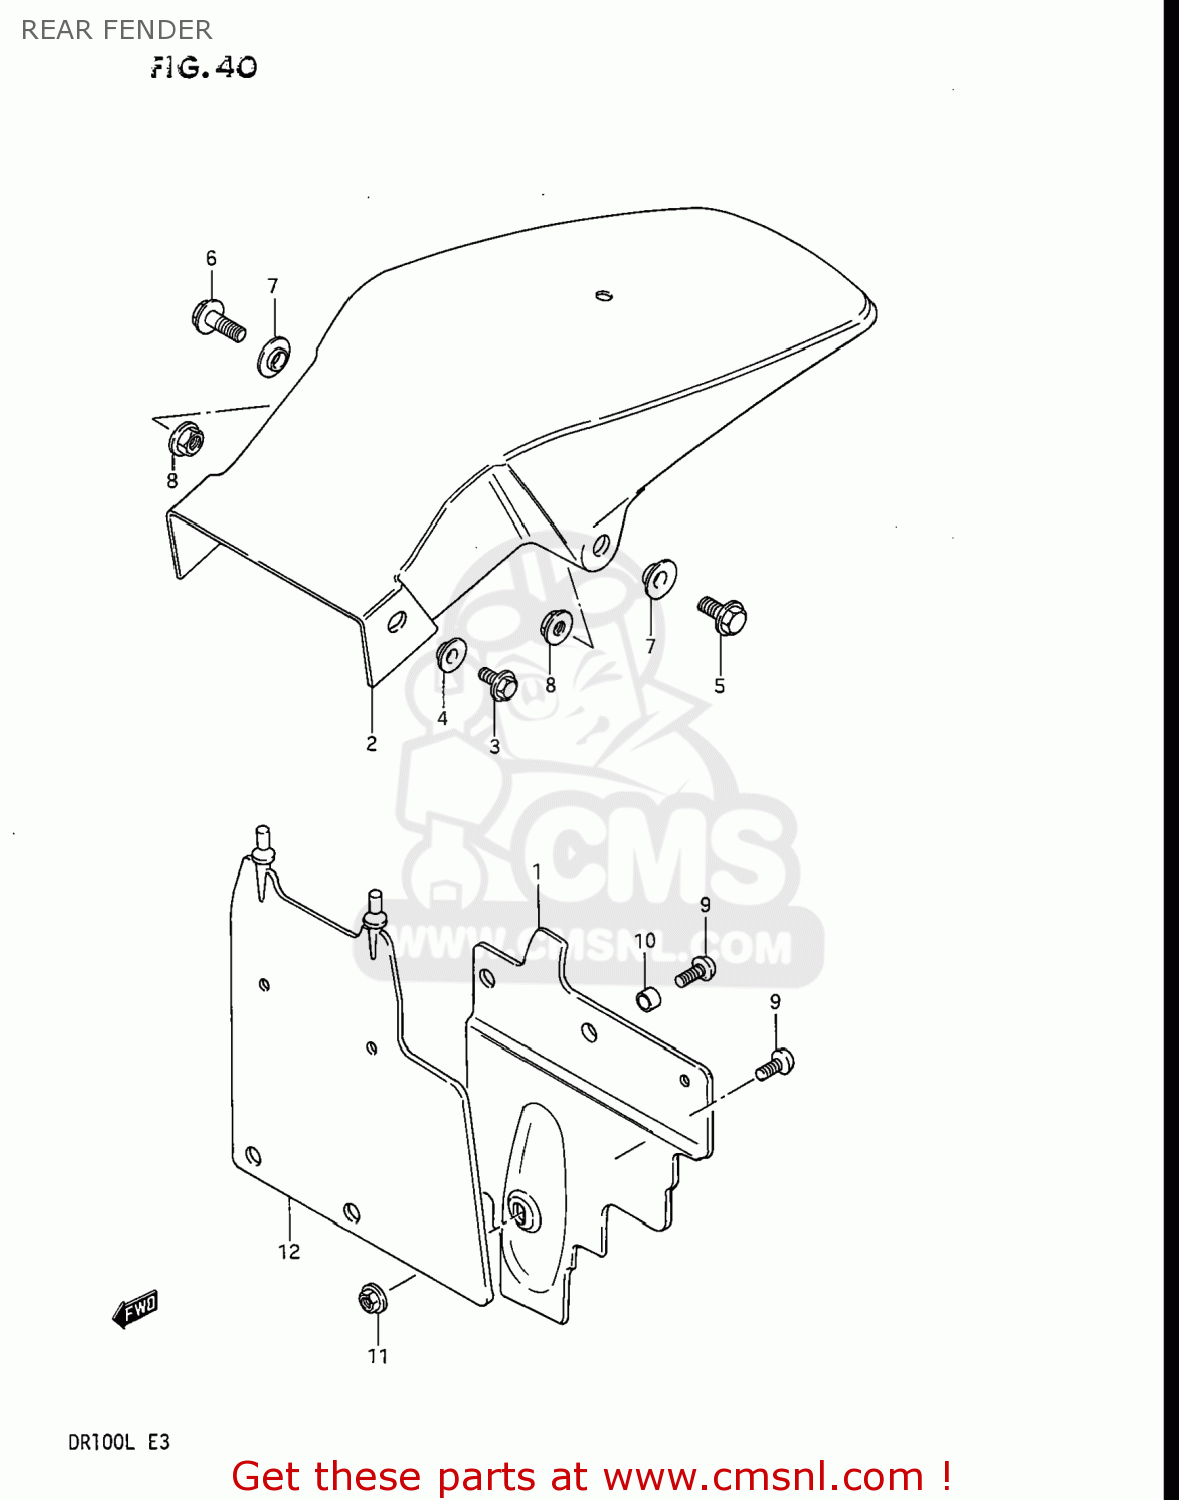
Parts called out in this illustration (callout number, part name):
1	FENDER, RR FR
2	FENDER,REAR
3	BOLT 6X16
4	WASHER
5	BOLT
6	BOLT
7	WASHER
8	NUT
9	SCREW
10	SPACER
11	NUT
12	MUD GUARD,REAR FENDER
